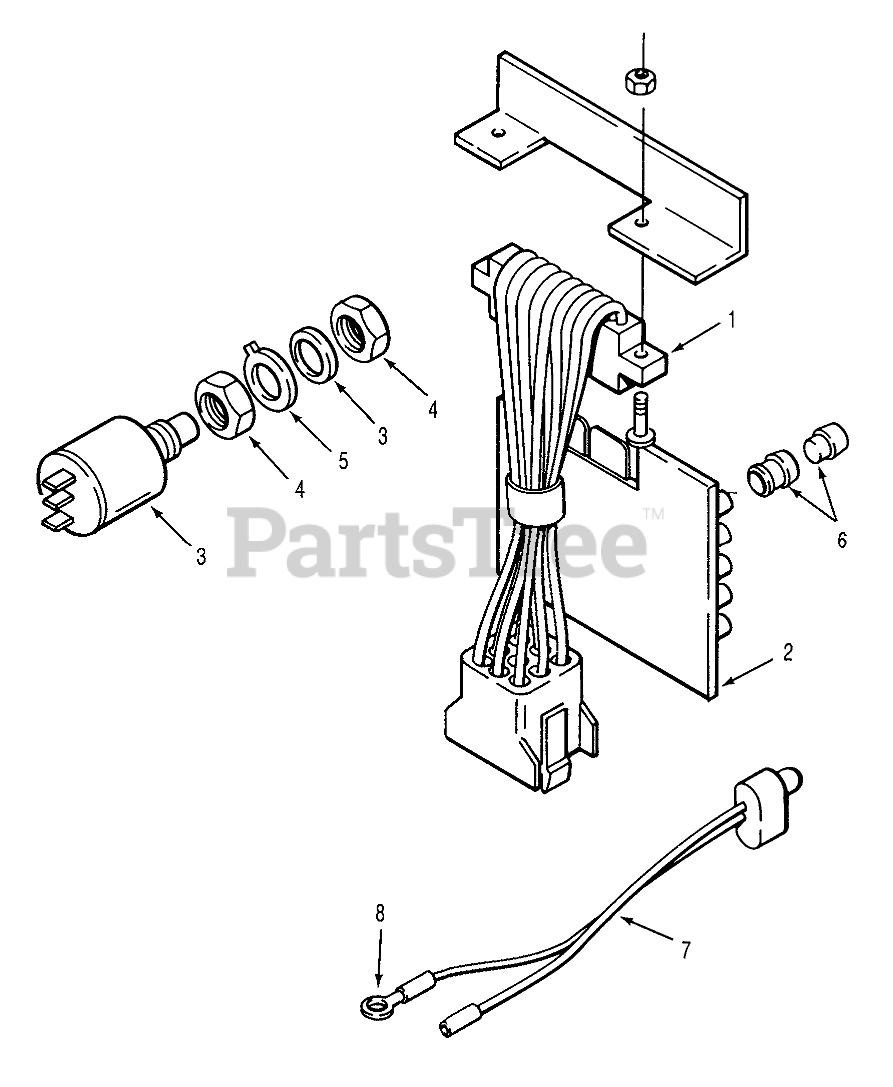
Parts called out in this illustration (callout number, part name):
1	P.C.-BOARD HARNESS
2	P.C. BRD & SCHEMATIC
3	SWITCH-PUSH BUTTON
4	NUT F/W 116796
5	Washer
6	ASSY LENS & BUSHING
7	LIGHT-INDICATOR
8	ASSY WIRE INDICATOR
